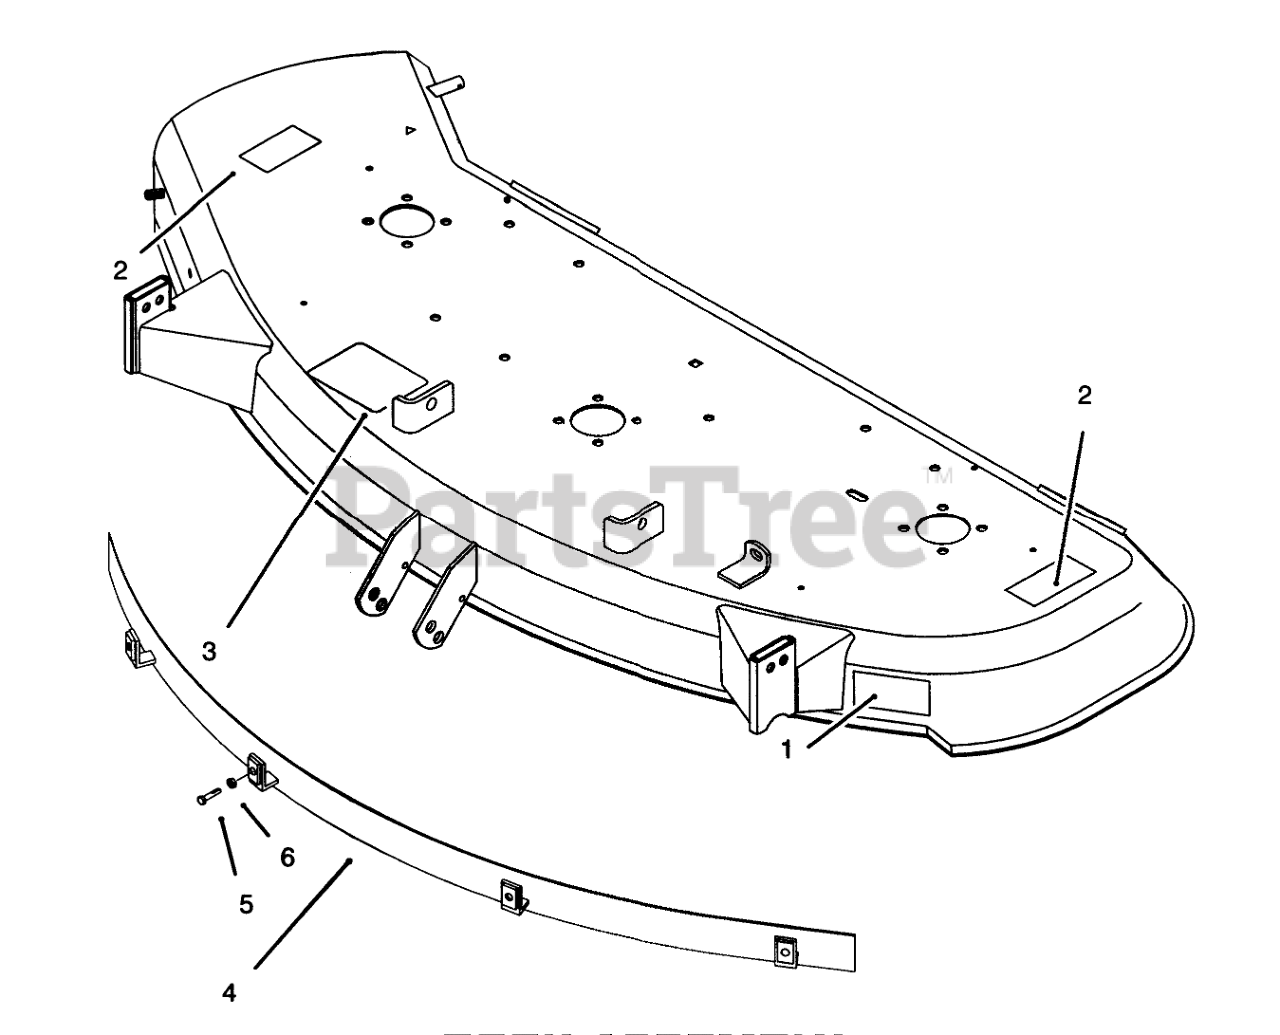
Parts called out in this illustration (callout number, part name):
1	DECAL-ADJUSTMENT, WHEEL
2	DECAL-DANGER
3	Decal-Belt Installation
4	Shield
5	Screw-Hex Hd.
6	NUT-JAM
